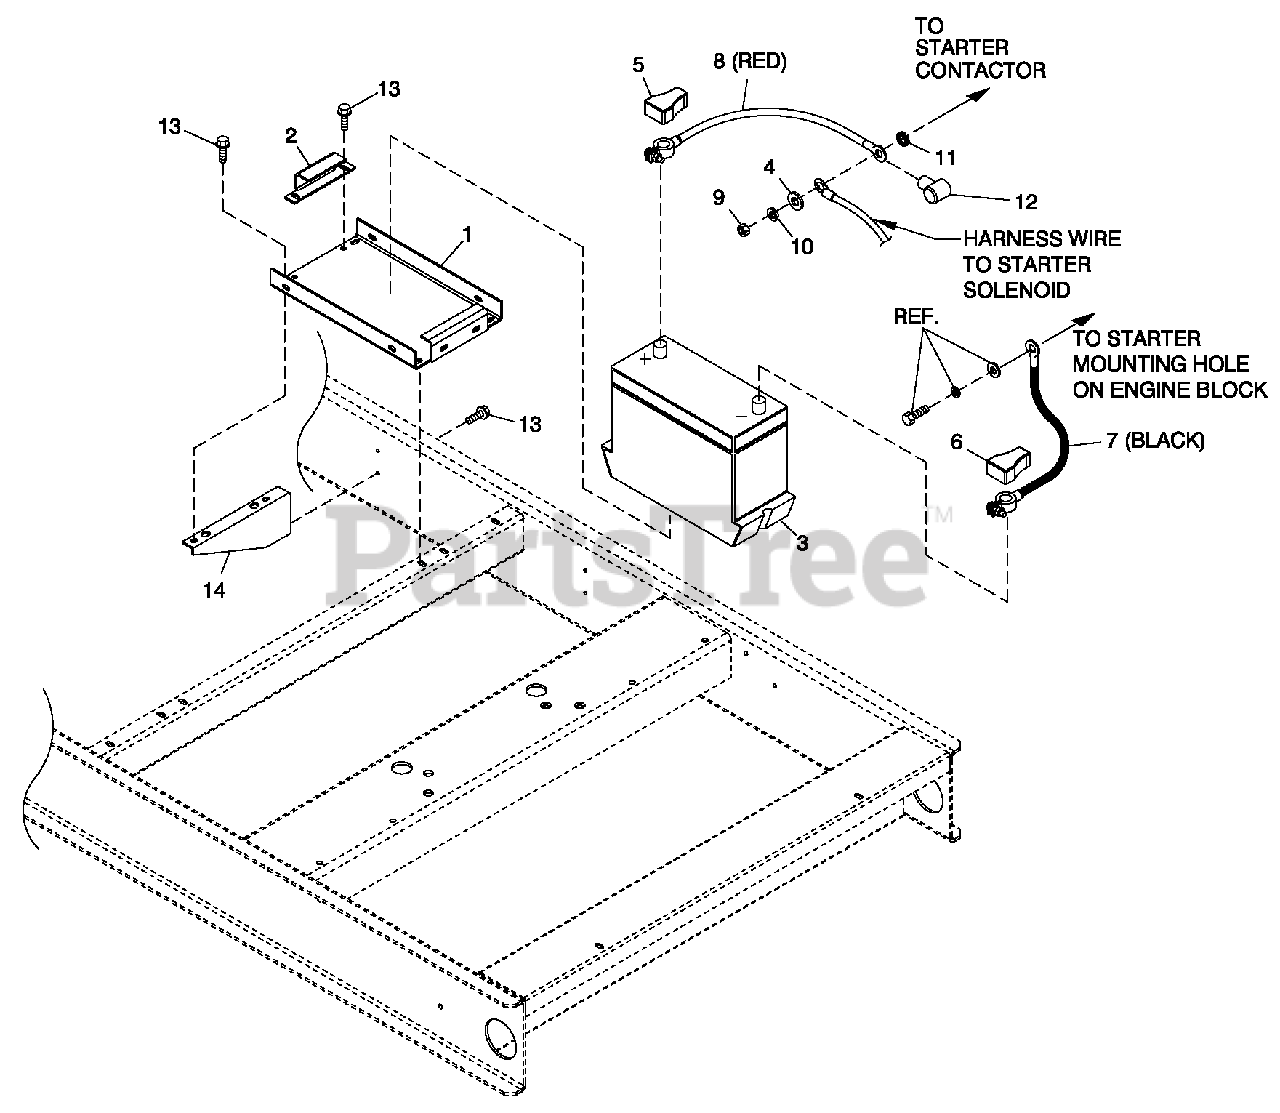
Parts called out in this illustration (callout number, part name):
1	TRAY BATTERY
2	STRAP BATTERY RETAINMENT
3	BATT 12VDC 24F 625
4	WASHER FLAT 3/8-M10 ZINC
5	BATT POST COVER RED +
6	BATT POST COVER BLK -
7	CABLE BATT BLK #1 X 18.00
8	CABLE BATT RED #1 X 28.00
9	NUT HEX M 8-1.25 G8 YEL CHR
10	WASHER LOCK M8-5/16
11	WASHER SHAKEPROOF EXT 5/16 STL
12	BOOT BATTERY CABLE
13	SCREW THF M6-1X16 N WA Z/JS
14	SUPPORT BATTERY TRAY
